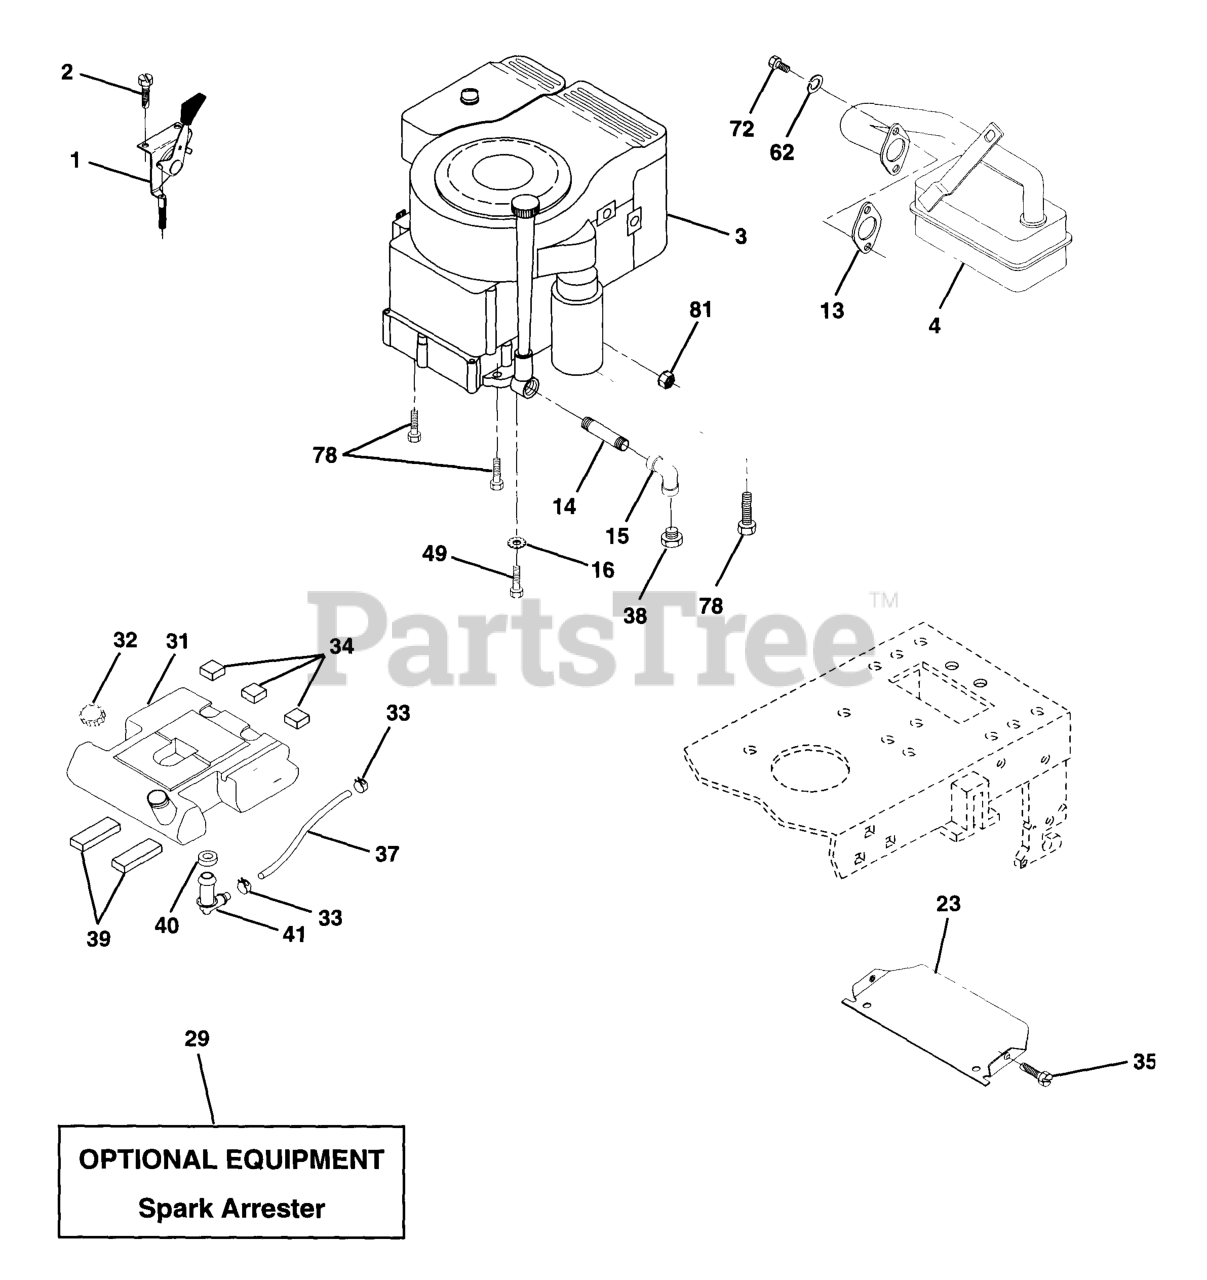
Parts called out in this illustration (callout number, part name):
1	CHOKE CONTROL
2	SCREW LT
4	MUFFLER.LT.BRIGGS.14HP.IC/OHV
13	GASKET.ENG.1.313 ID.TIN PLATED
14	Nipple Pipe 3/8 Npt X 3"
15	ELBOW
16	LOCKWASHER
23	SHIELD HEAT
29	KIT.SPARK ARRESTOR 794945 B&S
31	FUEL TANK
32	FUEL CAP
33	HOSE CLAMP
34	PAD-SPACER LT
35	SCREW.THDROL.5/16-18X3/4.TTY
37	HOSE T
38	Plug Oil Drain (Order From Engine Manufacturer)
39	PAD IDLER TI
40	BUSHING OUTLET T
41	STEM FUEL TANK
49	SCREW GTV
62	WASHER.LOCK.HVY.HLCL.SPR.5/16
72	SCREW
78	SCREW
81	NUT FLANGE 1/4-20 STARTER NUT
